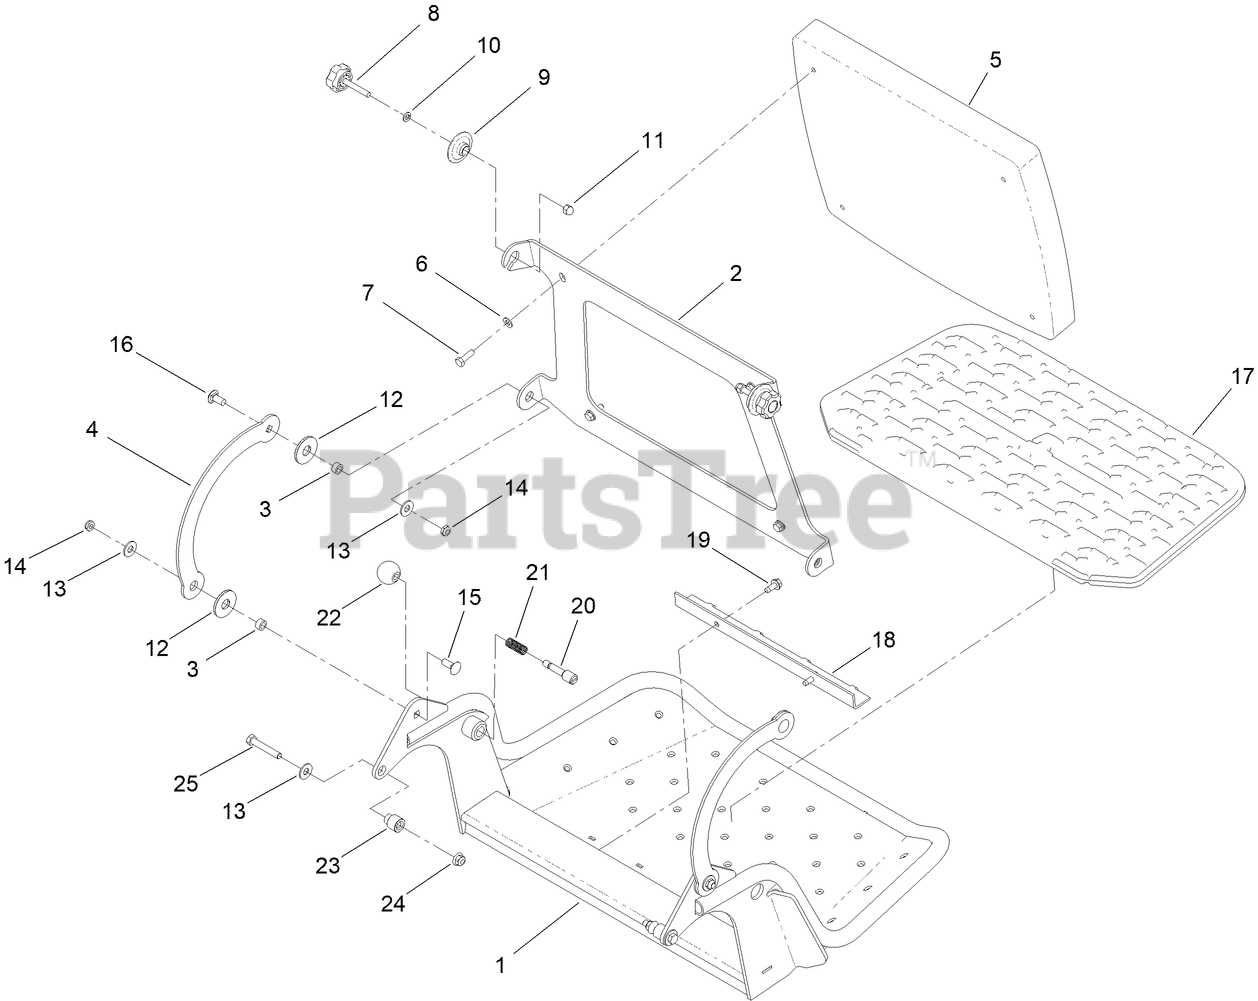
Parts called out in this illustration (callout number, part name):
1	PLATFORM
2	HINGE-PAD
3	SPACER
4	LINK-PAD
5	CUSHION PAD ASM
6	WASHER-PLAIN
7	SCREW-HH
9	SLIDE-BUSHING
10	WASHER-LOCK
11	NUT-ACORN
12	WASHER-FRICTION, COMPOSITE
13	WASHER-FLAT
15	BOLT-CARR
16	SCREW-CARR
17	MAT, PLATFORM
18	CLAMP-SHIELD
19	SCREW-HWHTF
20	PIN-LATCH
21	SPRING
22	KNOB-BALL
23	BUSHING-FLANGED
24	NUT-HF, NI
25	SCREW-HH
